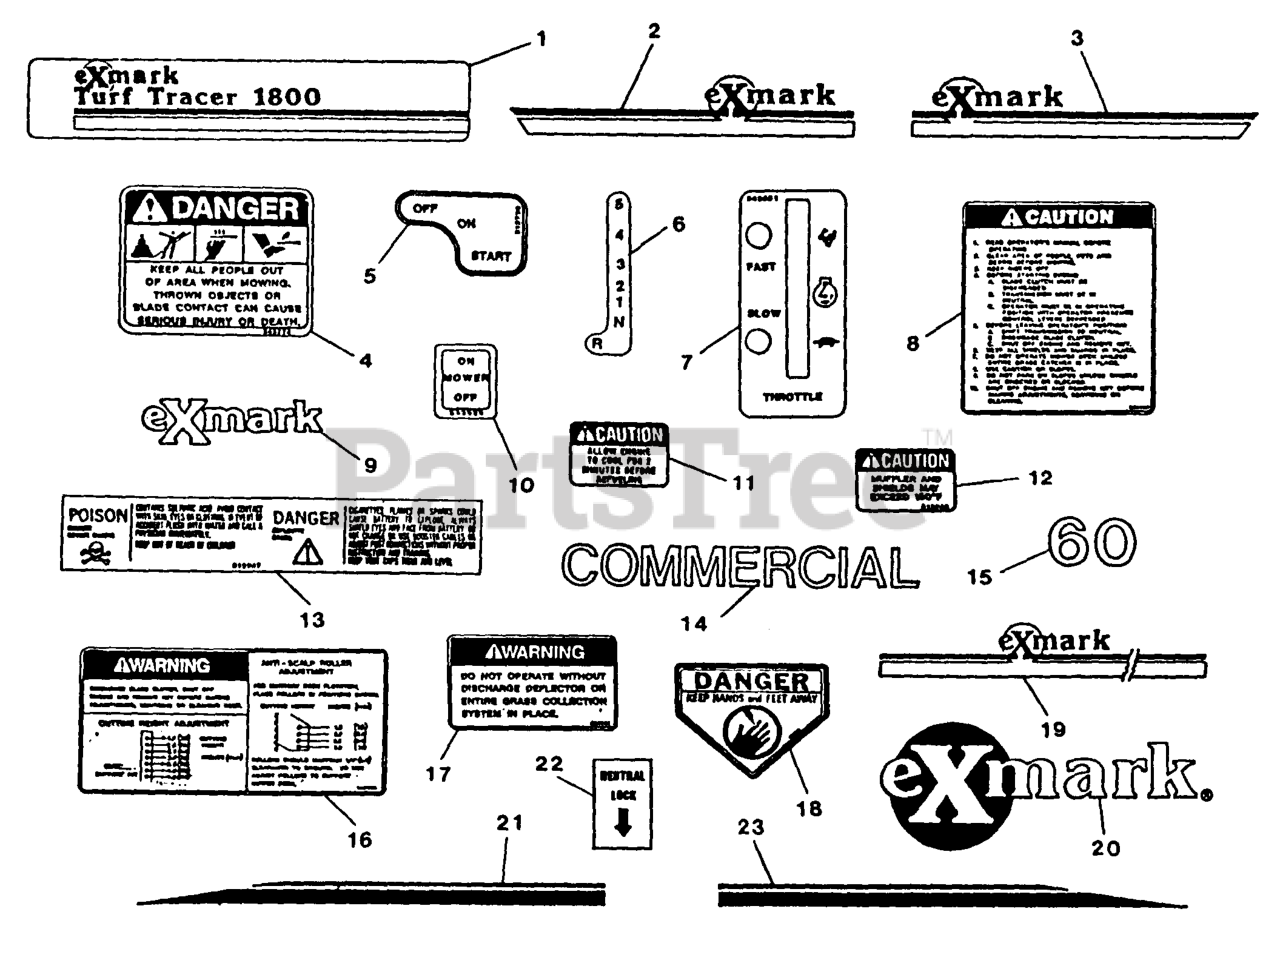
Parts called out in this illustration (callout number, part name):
4	DECAL-DANGER
10	DECAL-MOWER SWITCH
13	DECAL-BATTERY
18	DECAL-DANGER
22	DECAL,NEUTRAL LOCK
